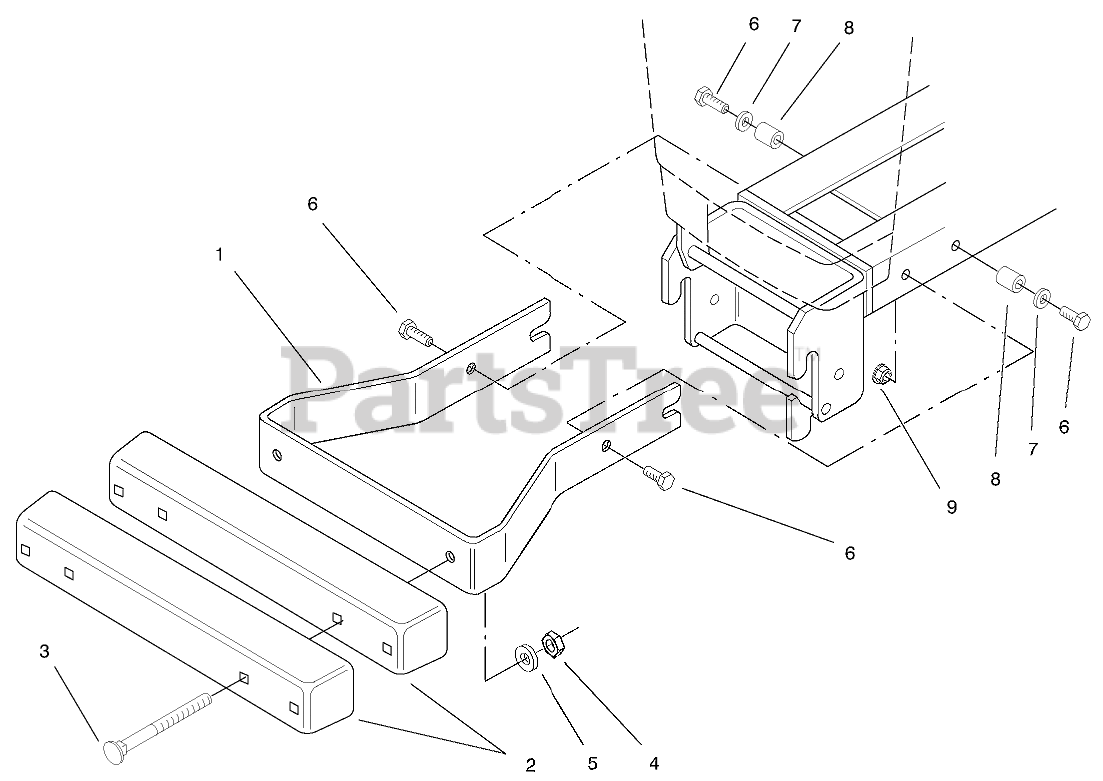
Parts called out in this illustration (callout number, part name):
1	FRAME-WEIGHT R
2	FRONT WEIGHT B
3	Bolt-Carriage
4	Nut
5	WASHER
6	Bolt
7	Washer
8	SPACER
9	NUT-FLANGE
